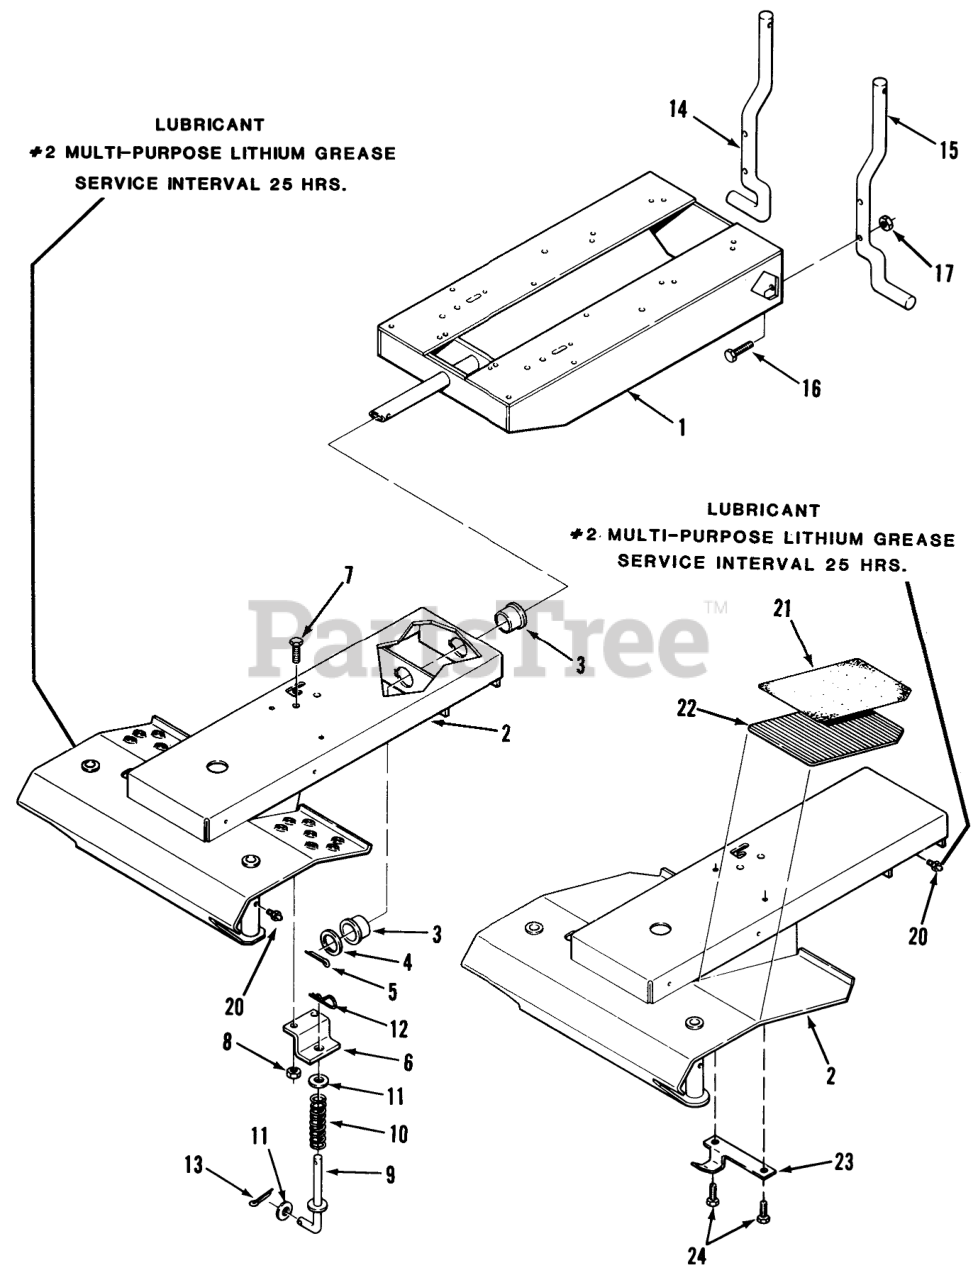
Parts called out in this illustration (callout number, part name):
1	ASS'Y-FRAME REAR R
2	Front Frame Assy
3	BEARING FLANGE
4	WASHER
5	Pin-Cotter
6	BRACKET R
7	Bolt
8	NUT
9	ROD ASSY R
10	SPRING-COMPRESSION
11	Washer
12	Hairpin Cotter
13	Cotter Pin
14	REAR ROD RH B
15	REAR ROD LH B
16	BOLT 5/16-18X1 1/2
17	Nut
20	Grease Zerk
21	PAD FOOTREST RH
22	PAD FOOTREST RH
23	BRACKET-SWITCH R
24	Screw
